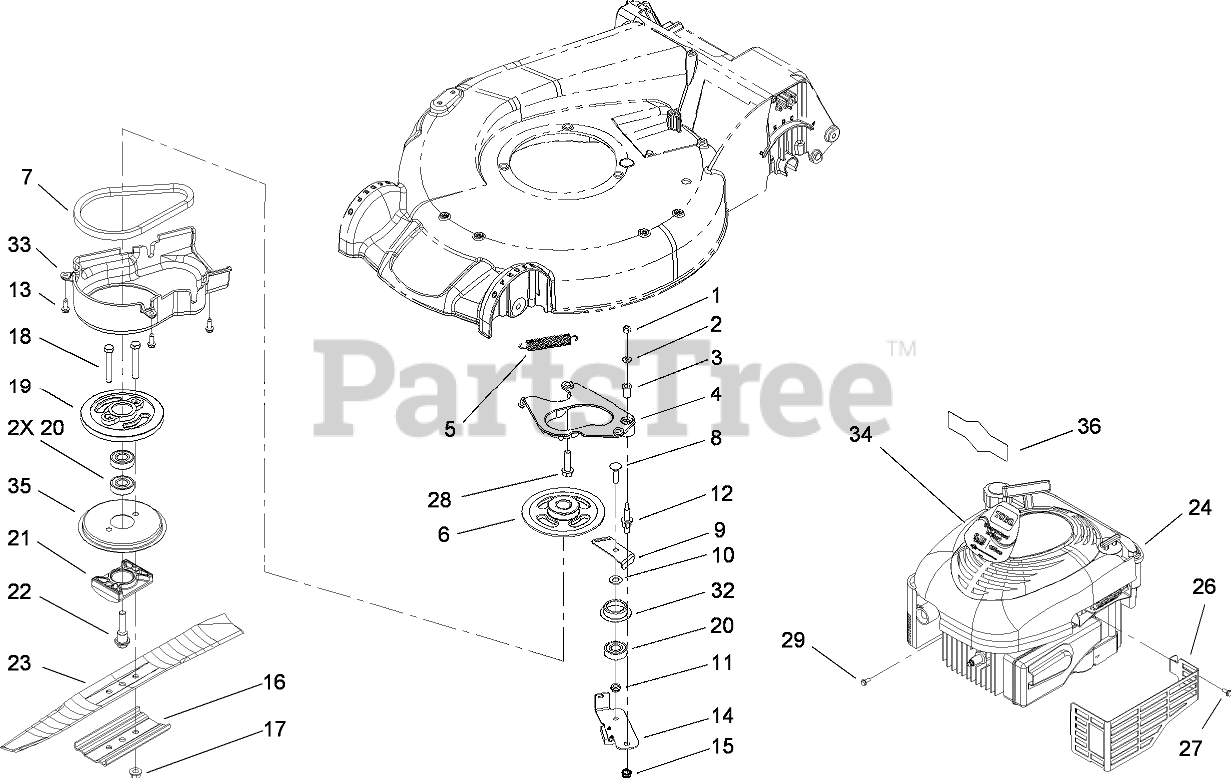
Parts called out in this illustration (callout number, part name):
1	NUT-LOCK, NI
2	WASHER-FLAT
3	BUSHING
4	PLATE-ANCHOR
5	SPRING-TENSION, BRAKE
6	PULLEY
7	BELT
8	BOLT-CARR
9	PLATE-GUIDE
10	WASHER-PLAIN
11	SPACER-BEARING
12	BOLT-SHOULDER
13	SCREW-HWHTF
14	BRAKE ARM ASM
16	SUPPORT-BLADE
17	NUT-LOCK
18	SCREW-HH
19	DRUM
20	BEARING-BALL
21	SUPPORT-BLADE
22	BOLT-CRANK
23	BLADE-RECYCLING
26	SHIELD-MUFFLER
27	SCREW-TAPTITE
28	SCREW-HWH
29	SCREW-HWH
32	RETAINER-BELT
34	DECAL-ENGINE
35	DISC
36	DECAL-RECOIL
